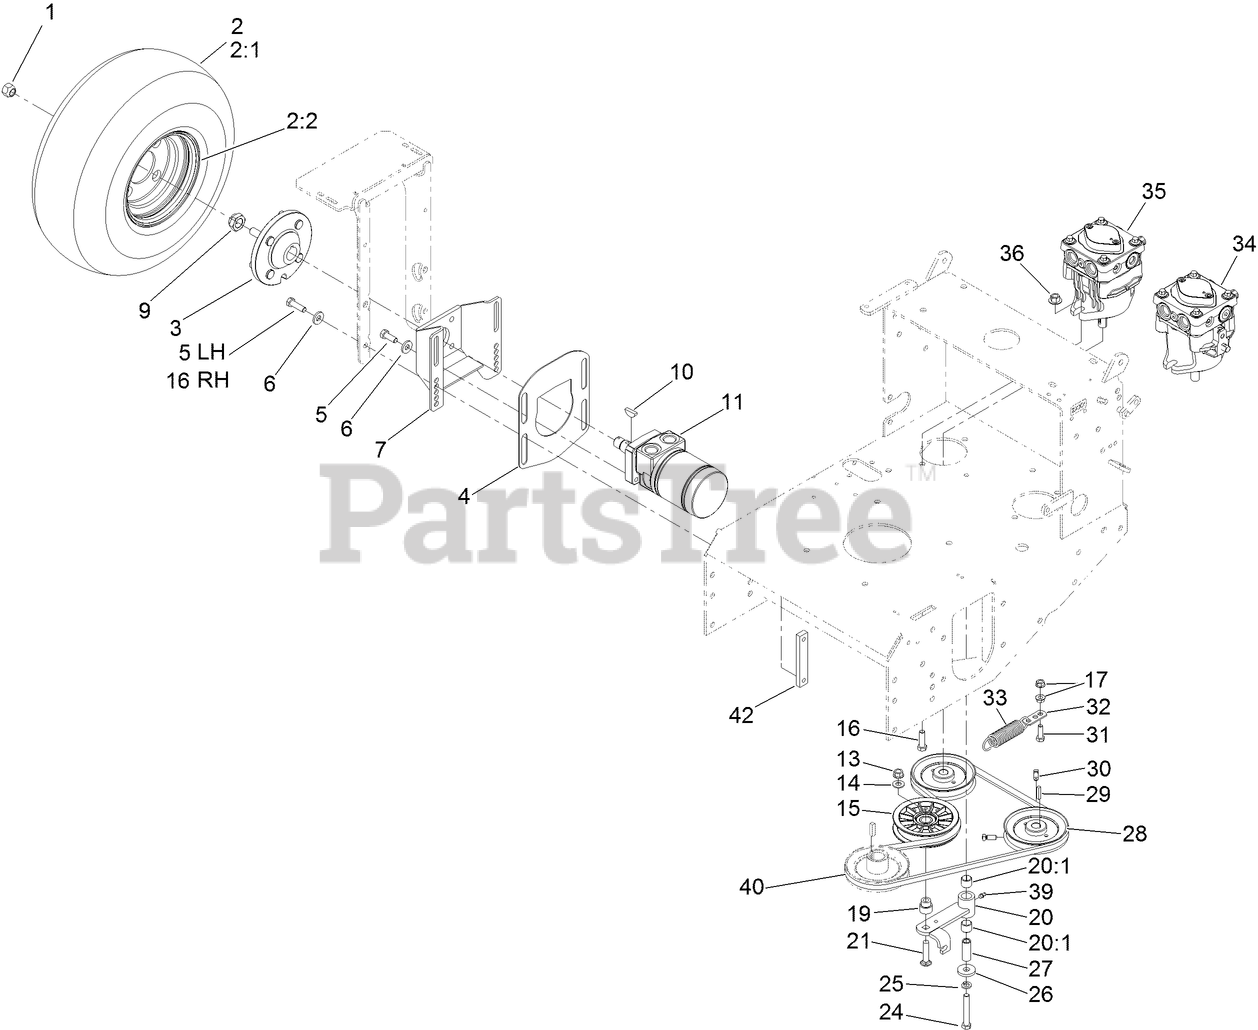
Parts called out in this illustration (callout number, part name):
1	NUT-LUG
2	Wheel And Tire ASM
2:1	Tire-Turfmaster
2:2	Wheel-Rim
3	WHEEL HUB ASM
4	GUARD-DEBRIS
5	SCREW-HH
6	WASHER-BELLEVILLE
7	Mount-Motor
9	NUT-LOCK
10	Key-Woodruff
11	HYD MOTOR ASM
13	NUT-HF
14	WASHER-FLAT
15	PULLEY-IDLER, FLAT
16	SCREW-HH
17	NUT-HF
19	BUSHING-IDLER
20	Idler Arm ASM
20:1	SLEEVE-BEARING
21	SCREW-CARR
24	SCREW-HH
25	WASHER-LOCK
26	WASHER
27	BUSHING
28	SHEAVE ASM
30	SCREW-SET
31	SCREW-HH
32	Anchor-Spring
33	SPRING-EXTENSION
34	LH HYD PUMP ASM
35	RH HYD PUMP ASM
36	NUT-FLANGE
39	FITTING-GREASE
40	V-BELT
42	BAR-NUT
